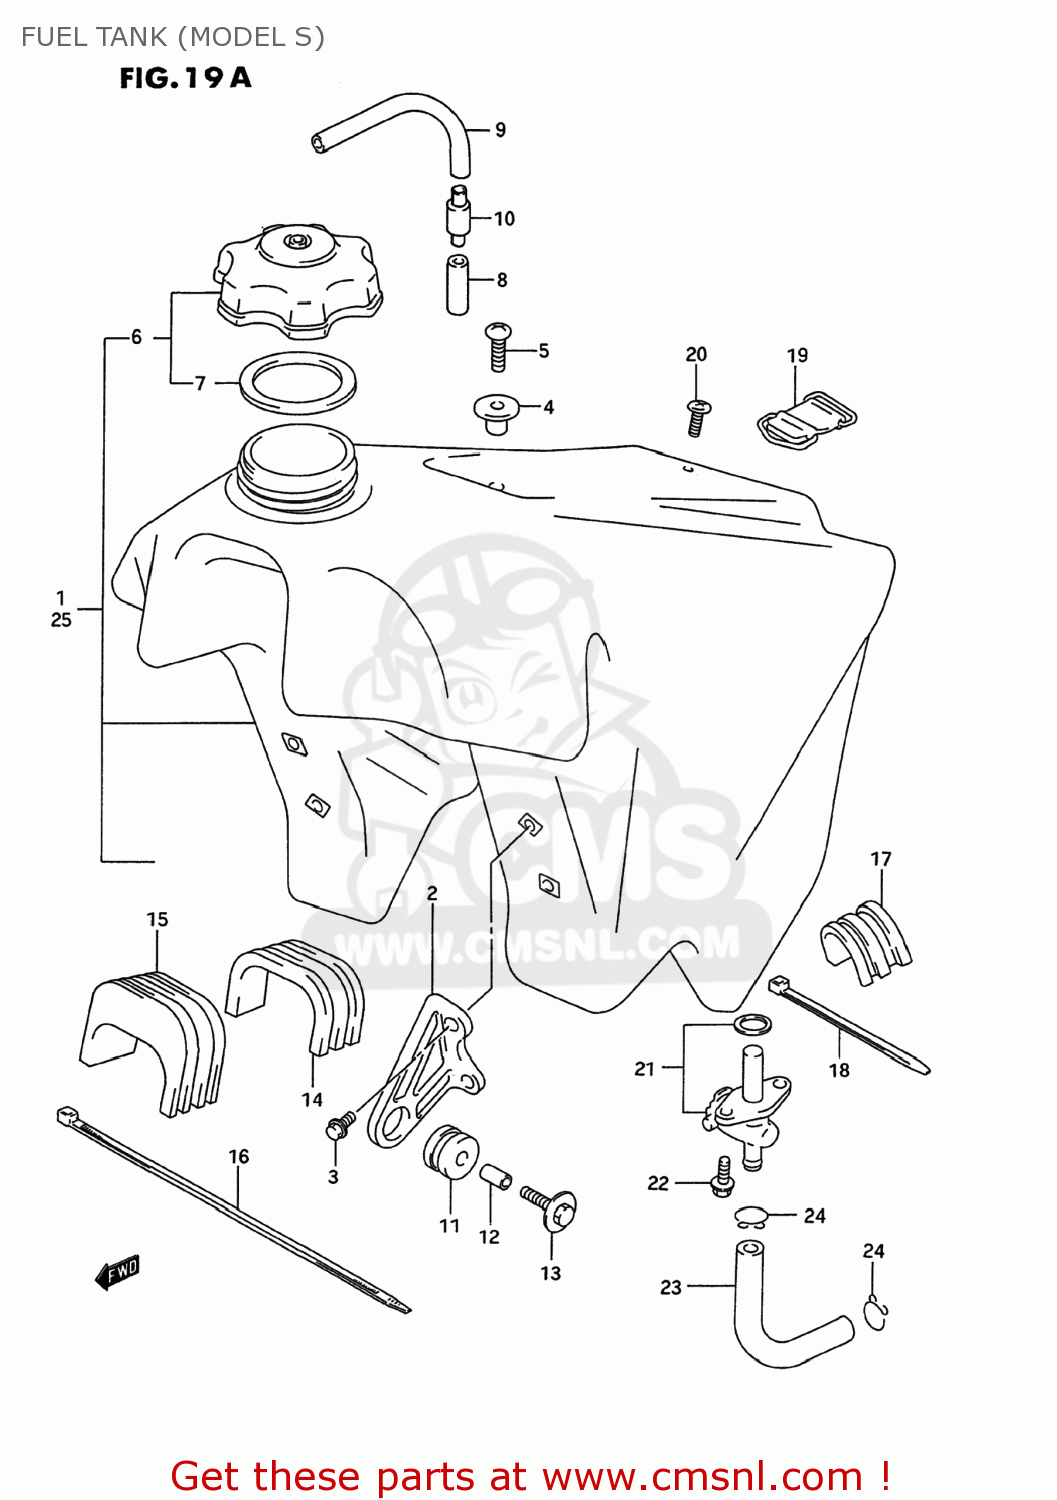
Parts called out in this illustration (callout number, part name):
1	TANK SET,FUEL
2	BRACKET,FUEL TANK,FRONT
3	BOLT
4	HOOK,SEAT FR
5	SCREW
6	CAP SET,FUEL TANK
7	GASKET,CAP (NAS)
8	HOSE(5X8.2X600)
9	HOSE(5X8.2X600)
10	SCREW
11	CUSHION,MUFFLER
12	SPACER (6.4X9X13.5)
13	BOLT(6X30)
14	CUSHION,FUEL TANK NO.2
15	CUSHION,FUEL TANK
16	CLAMP(L:300)
17	CUSHION,FUEL TANK NO.2
18	CLAMP(L:145)
19	BAND,FUEL TANK RR
21	COCK ASSY,FUEL
22	BOLT
23	HOSE(6.5X11.5X600)
24	CLIP
25	TANK SET,FUEL
